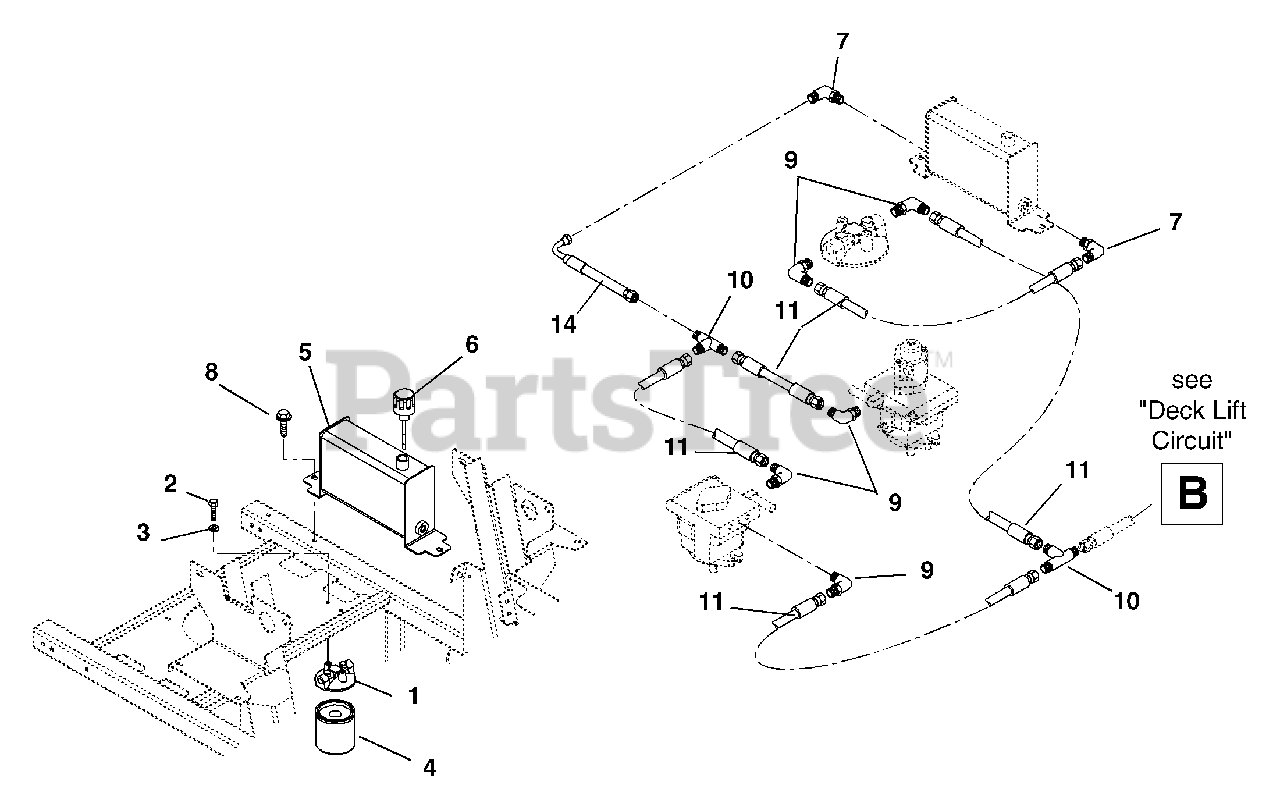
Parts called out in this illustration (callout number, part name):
1	Head-Filter
2	Bolt-Hex .25-20 x .50 Grade 5
3	Washer-Locking .25 x .062
4	Oil Filter
5	Tank-Hydraulic Weldment
6	Hydraulic Tank Dipstick
7	Fitting, Adapter
8	Screw-Tapping .38-16 x .75 Hex Washer Head
9	Adapter
10	Adapter-Tee .56-18
11	Hose-Hydraulic Valve to Tank
13	Adapter
14	Hose, Hydraulic
